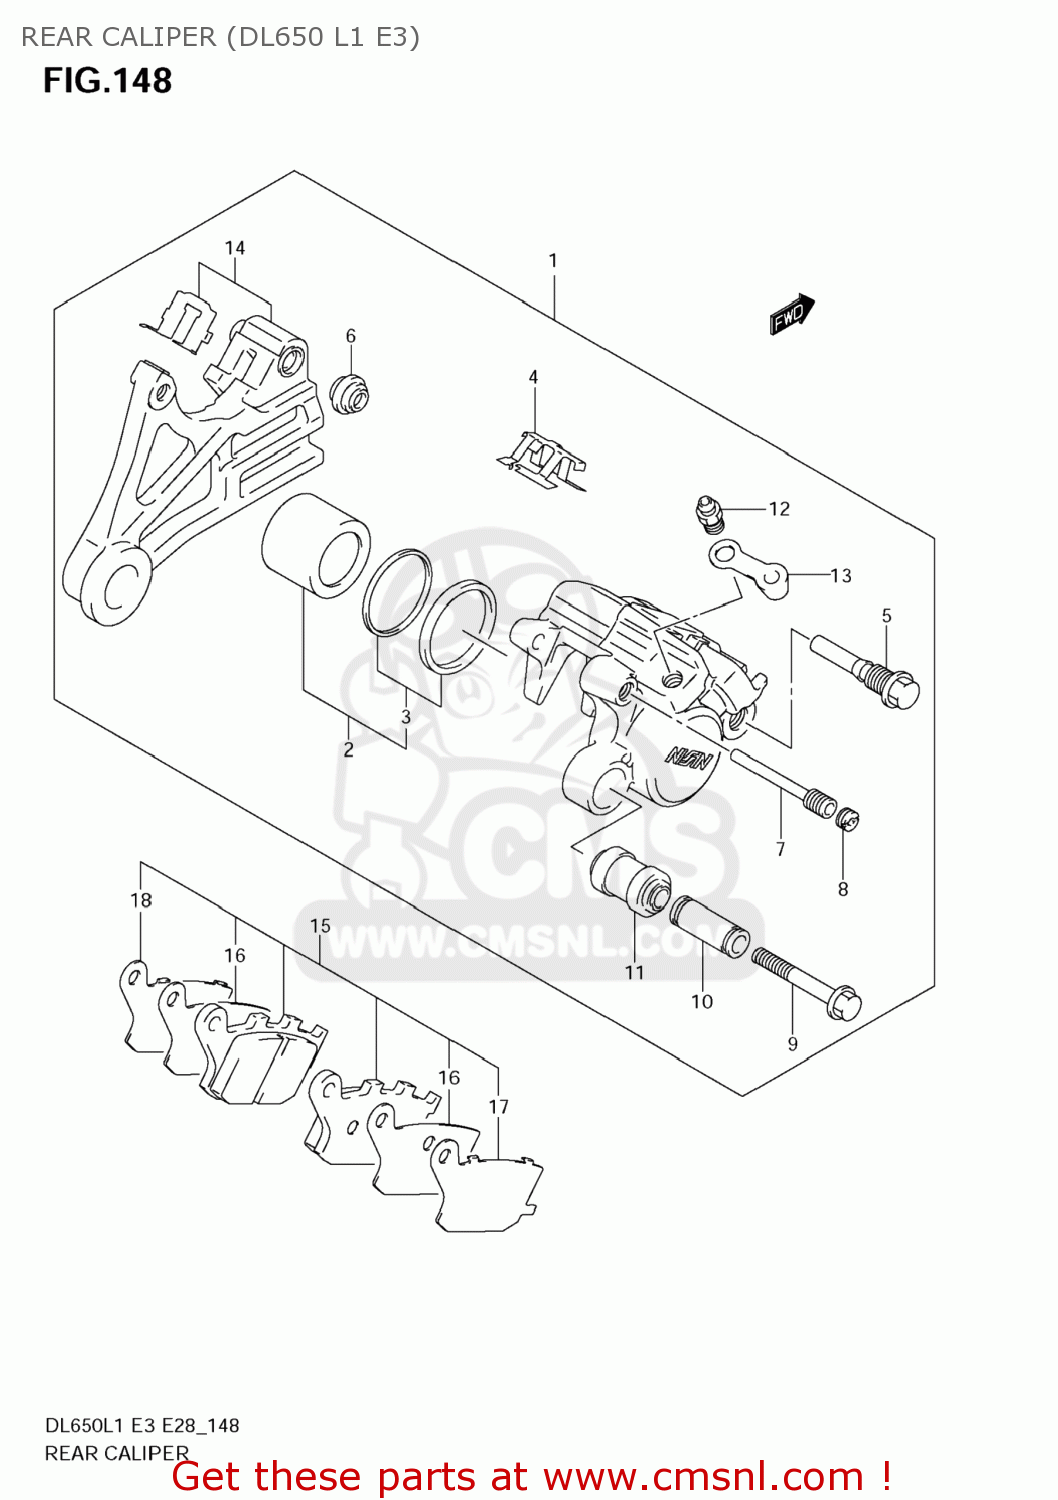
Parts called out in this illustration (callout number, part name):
1	CALIPER ASSY,RR
2	PISTON SET
3	SEAL SET,PISTON
4	SPRING,PAD
5	BOLT
6	BOOT
7	PIN,PAD
8	PLUG,PIN
9	BOLT
10	SLEEVE
11	BOOT,SLEEVE
12	BLEEDER
13	CAP,BLEEDER
14	BRACKET
15	PAD & RETAINER SET
16	INSULATOR
17	RETAINER
18	RETAINER
